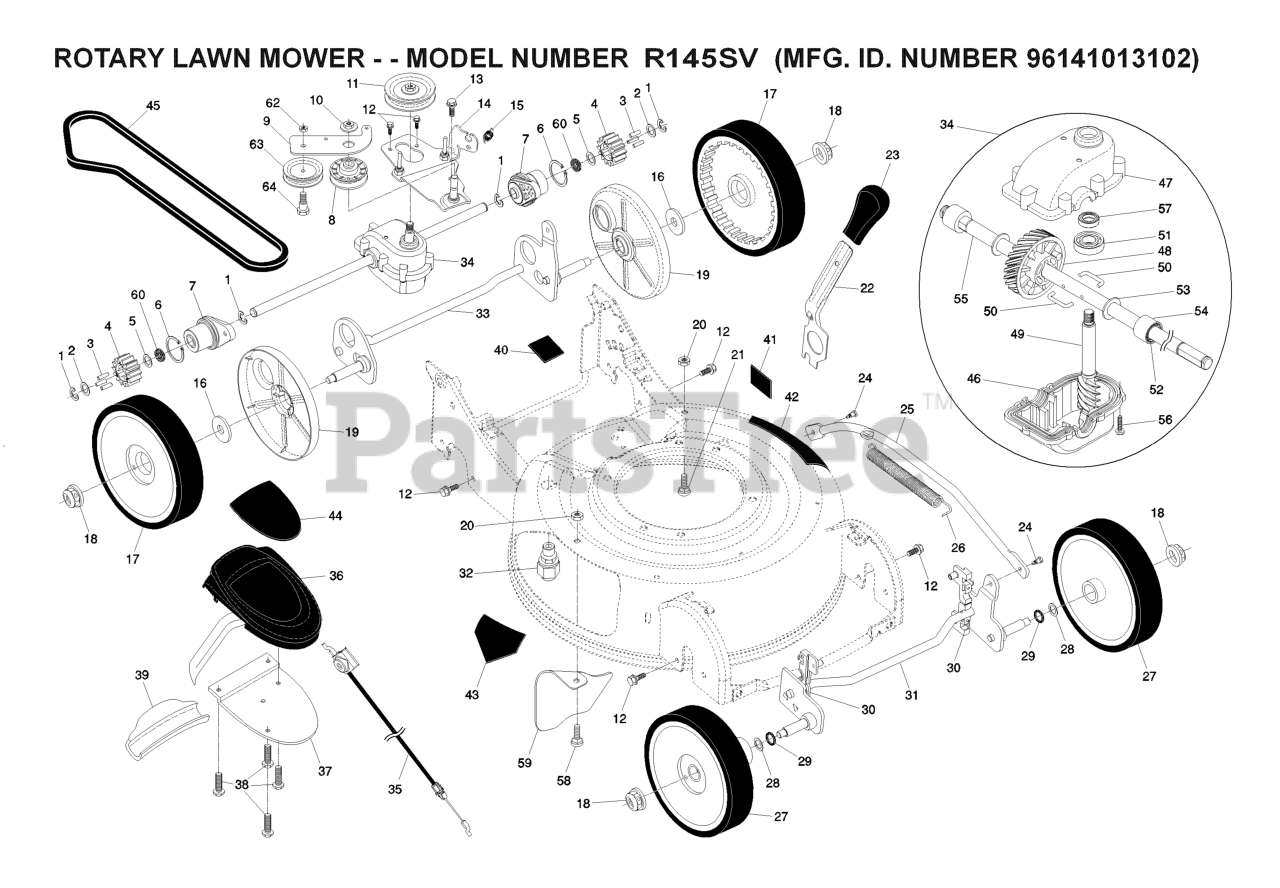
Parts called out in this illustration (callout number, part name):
1	E-RING 7/16 RE
3	PAWL.DRIVE.ETCHED
4	PINION.DRIVE.WALK
6	RETAINING RING (2 2)(3 2)
8	PULLEY.IDLER.V-BELT
9	ARM.IDLER.BZP
10	NUT.HEX.FLANGE.3/8-16.LOCKNUT
11	PULLEY.1.PIECE
13	SCREW 14-20 X 5/8
15	SPRING.RETURN
16	WASHER FLUT
17	WHEEL.8X1.75.H3SPK.RAD3.GY.BU3
18	NUT.HEX.FLANGE.3/8-16.LO(3 2)
19	COVER.DUST.WHEEL
20	NUT, HEX
21	BOLT.CARRIAGE.1/4-20 X 7/8
24	SHOULDER BOLT SEMI GIMLET PT.
26	SPRING EXTENSION
27	WHEEL & TIRES ASSY, FRONT
28	WASHER.FLAT.1/2
29	O-RING..070X.487.NEOPRENE
30	BUSHING.FRONT.TORQUE.S
36	CONTROL.DR.HV.RGD.GRY/BLU.45CM
37	BRACKET.DRIVE.CONTROL.MOUNT.BL
38	SCREW, PHILLIPS HEAD 10 X 5/8
43	DECAL.INTERNATIONL.CUTFINGER
46	CASE, LOWER
47	GEARCASE.HOUSING
48	GEAR.24.TOOTH.WALK.MOWER
50	WIRE, FORMED (15966)
52	SEAL.OUTPUT.SHAFT
57	SEAL INPUT SHAFT
62	NUT.CENTERLOCK.5/16-
63	IDLER PULLEY
64	SHOULDER BOLT
